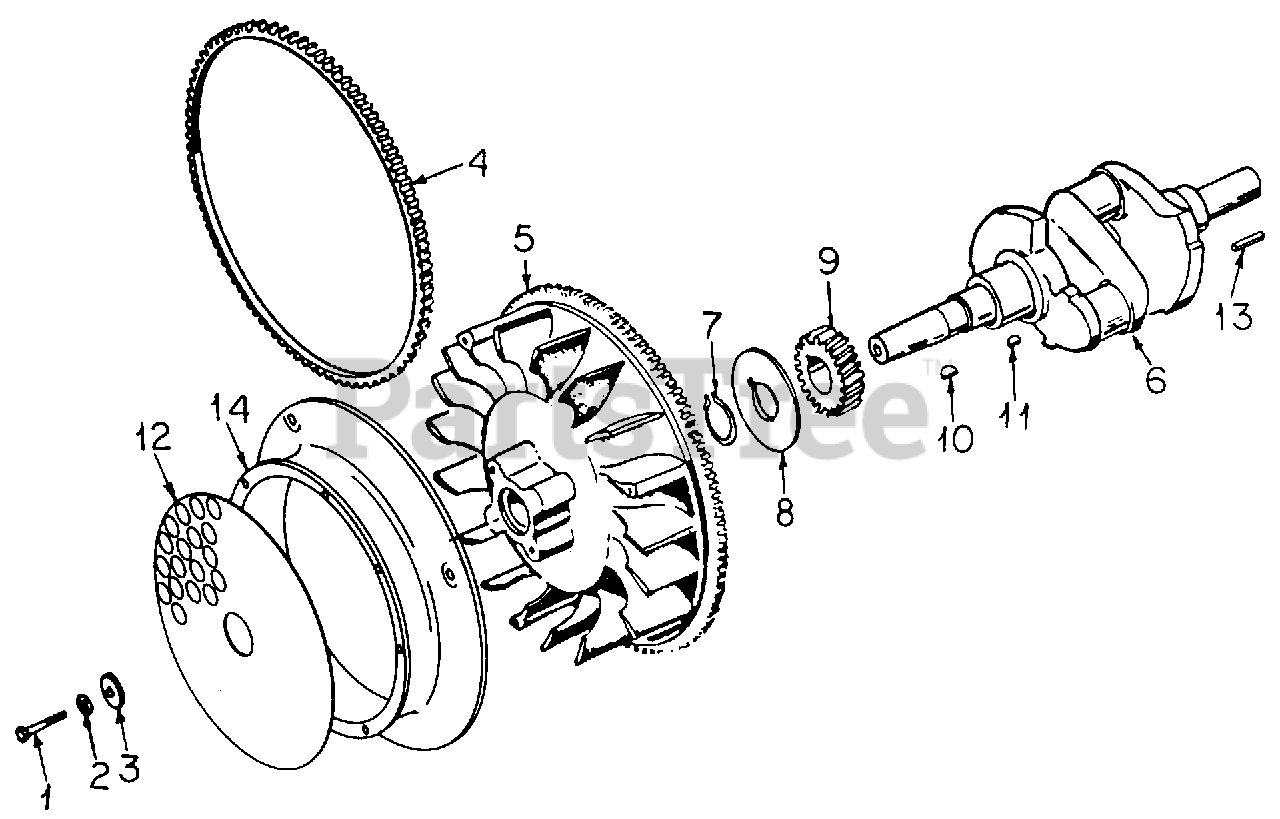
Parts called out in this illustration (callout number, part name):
2	Washer, 7/16 Lock
5	Flywheel Assy
7	Ring, Gear Retaining
8	Washer, Gear Retaining
9	Gear, Crankshaft
10	Key, Flywheel
11	Key, Crankshaft Gear
12	Guard, Flywheel
13	Key, Crankshaft Stub
14	Venturi, Blower Wheel
